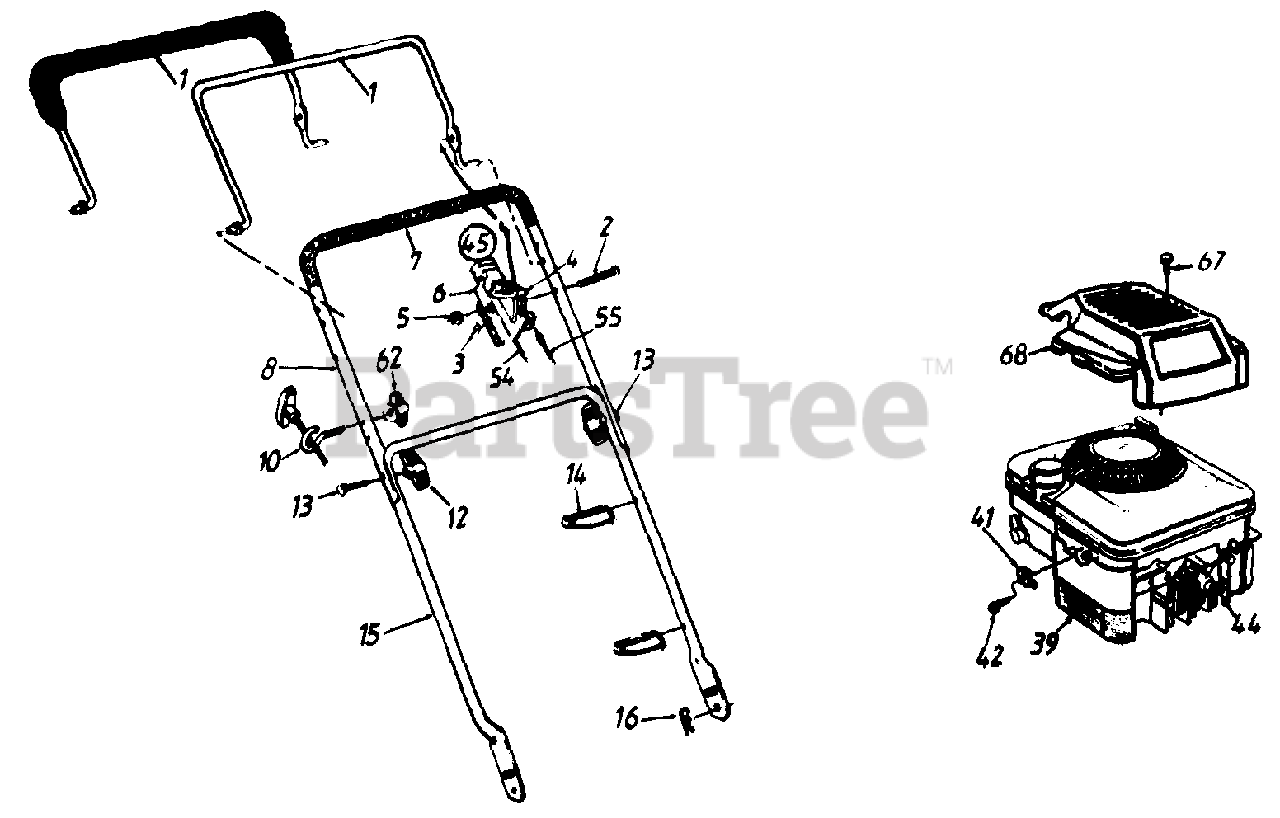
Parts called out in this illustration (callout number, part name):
1	Control Hdle Ass'y.
2	Oval C-Sunk Scr.
3	Spr. Wash. .66" I.D.
4	Throttle Lever
5	Hex L-Nut 1/4-20 Thd.
6	Throttle Body
7	Grip
8	Upper Handle
12	Hand Knob
13	Cur. Hd. Bolt 5/16-18 x 2" L.
14	Cable Tie
15	Lower Handle
16	Hairpin Cotter
39	Engine
41	Cable Clamp
42	Hex S Tap Scr. #10-32 x .62"
44	Spark Plug Boot
54	Throttle Cable 51" Lg.
55	Control Cable 36" Lg.
62	Handle Knob 1/4-20 Thd.
67	Hi-Lo Scr. #10 x 1.25" Lg.
68	Engine Shroud
